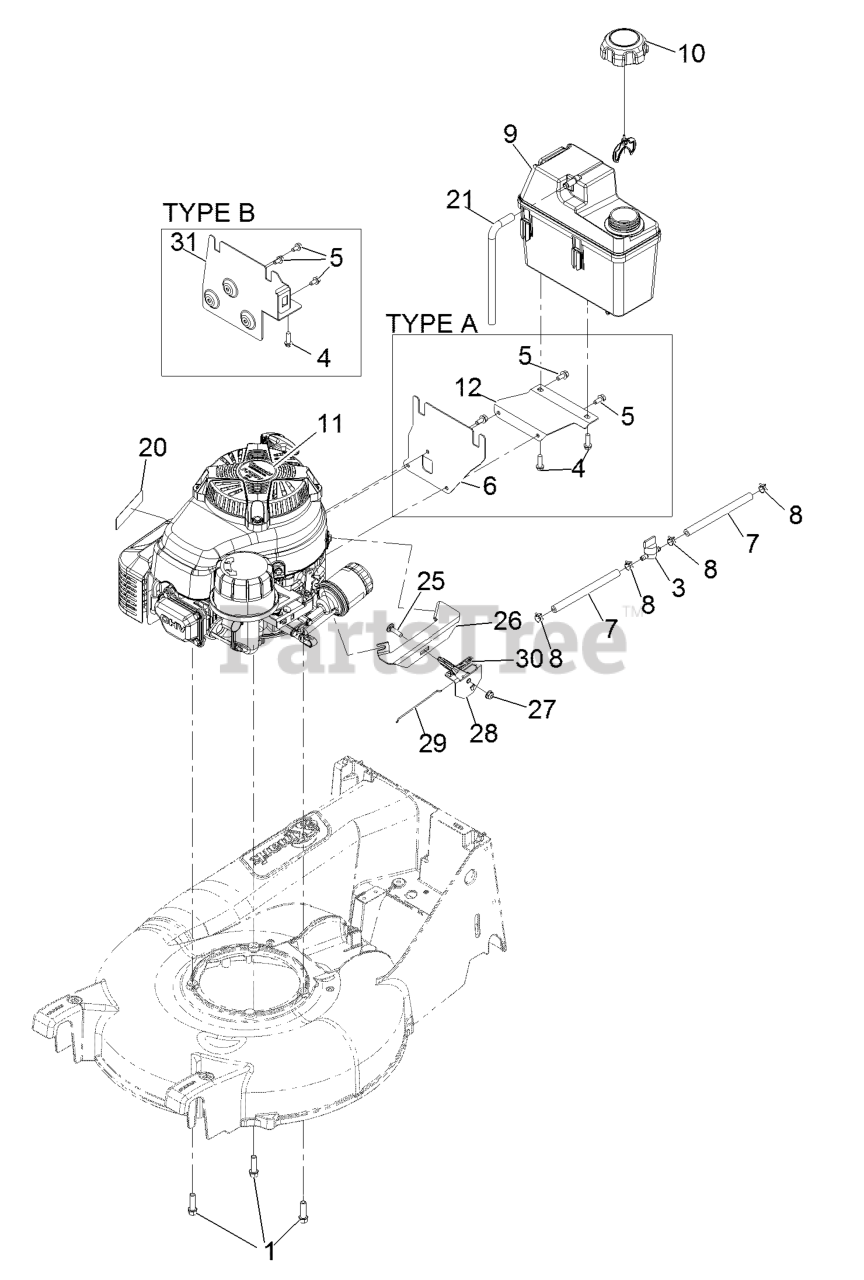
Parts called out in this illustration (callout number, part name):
1	SCREW-TAPTITE
3	VALVE-FUEL
4	SCREW-HWH
5	SCREW-HWH
6	BRACKET-TANK, MOUNTING
7	HOSE-FUEL
8	CLAMP-HOSE
9	TANK-FUEL
12	BRACKET-TANK, SUPPORT
20	DECAL-ARRESTER, SPARK
21	HOSE-VENT, CANISTER
25	SCREW-CARR
26	BRACKET-MOUNT, THROTTLE
28	CONTROL-THROTTLE
29	WIRE-CONTROL
30	DECAL-THROTTLE, CHOKE
31	BRACKET,FUEL TANK
